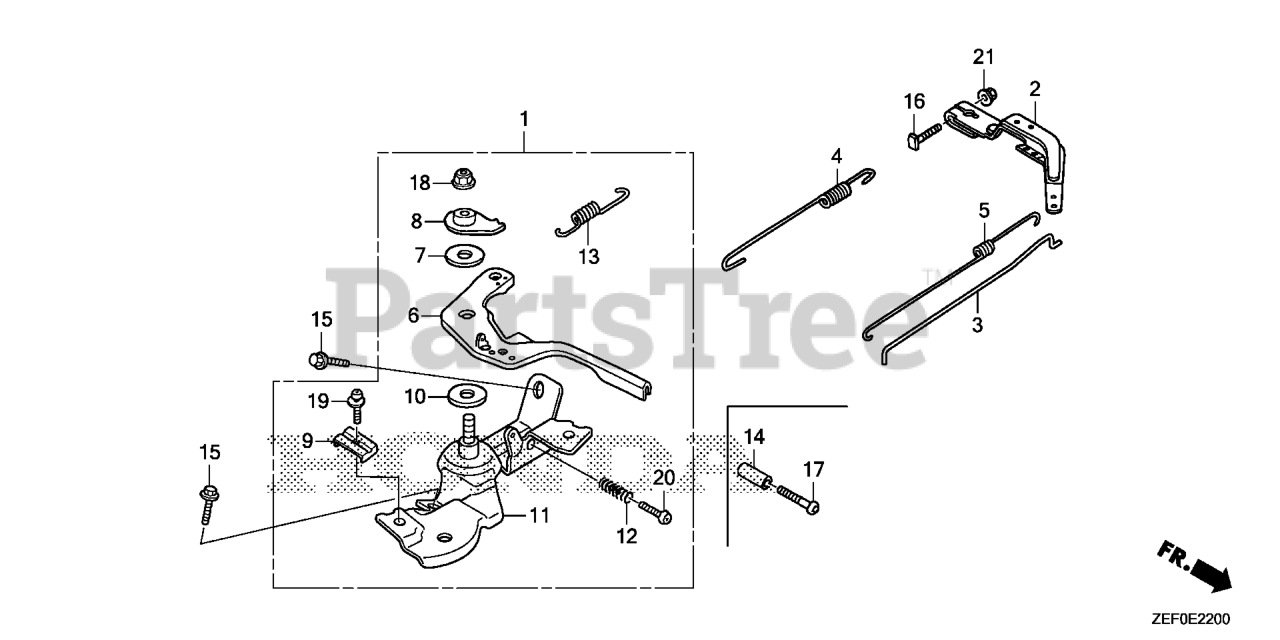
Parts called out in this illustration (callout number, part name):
1	CONTROL ASSY. (REMOTE)
2	ARM, GOVERNOR
3	ROD, GOVERNOR
4	SPRING, GOVERNOR
5	SPRING, THROTTLE RETURN
6	LEVER, CONTROL
7	SPRING, LEVER
8	WASHER, CONTROL LEVER
9	HOLDER, CABLE
10	SPACER, CONTROL LEVER
11	BASE, CONTROL
12	SPRING, CONTROL ADJUSTING Use from Engine SN 2327377.
13	SPRING, CABLE RETURN
15	BOLT, FLANGE (6X12) (CT200)
16	BOLT, GOVERNOR ARM
18	NUT, SELF-LOCK (6MM)
19	SCREW, PAN (5X16)
20	SCREW, PAN (5X25)
21	NUT, FLANGE (6MM)
